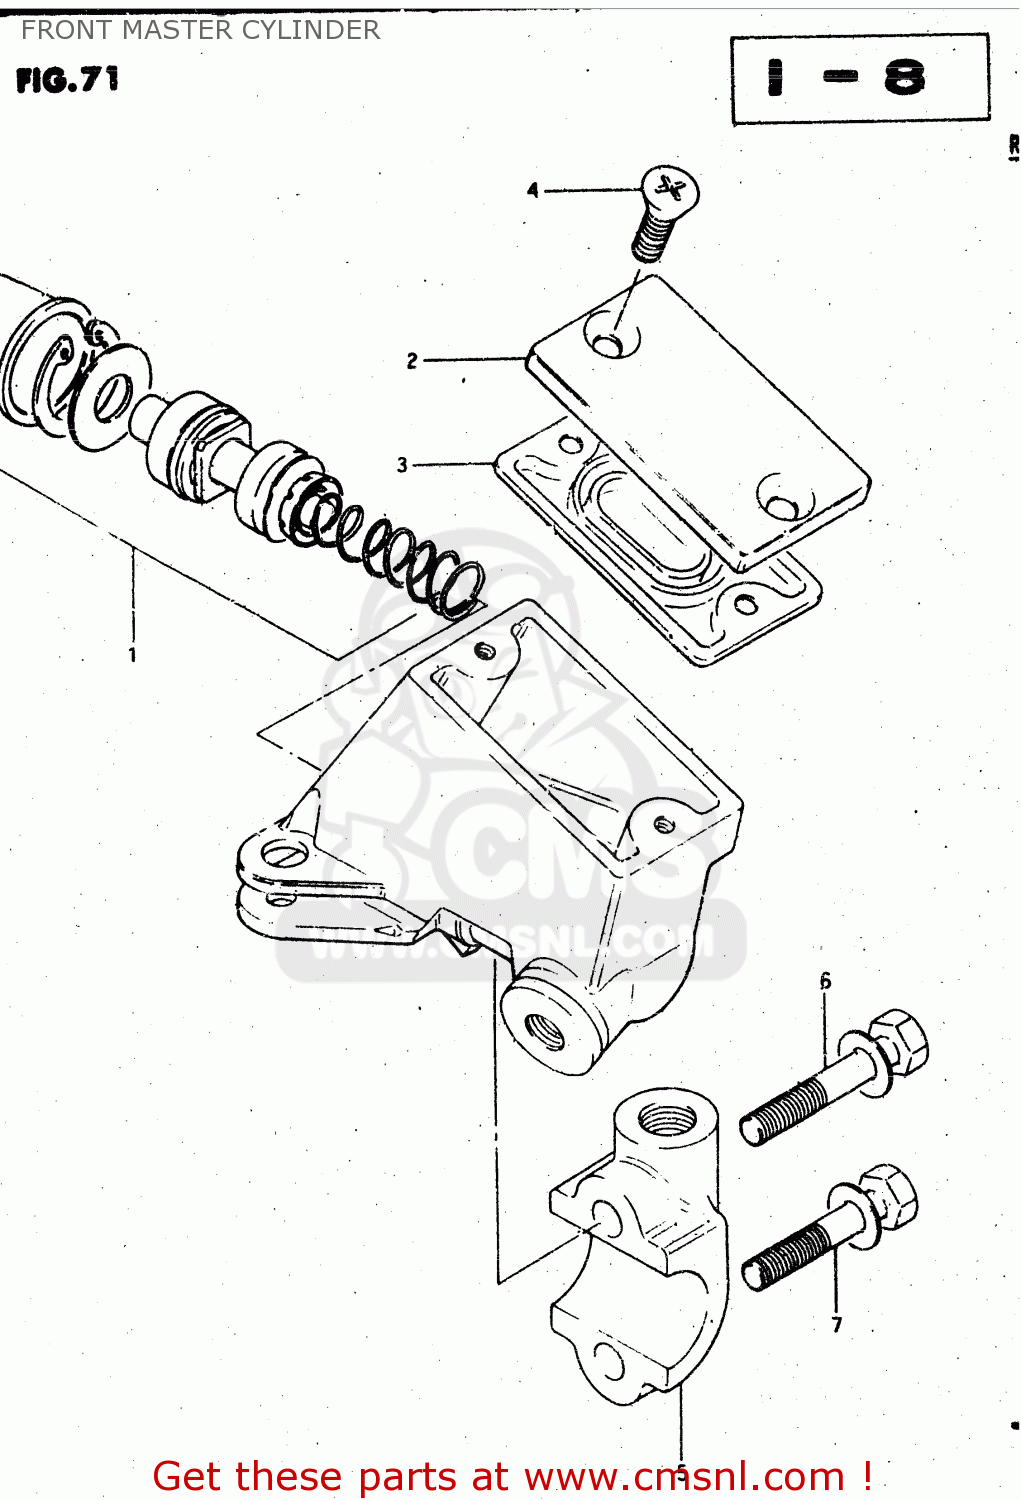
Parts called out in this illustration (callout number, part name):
1	PISTON & CUP SET
2	CAP
3	DIAPHRAGM,MASTER CYLINDER
4	SCREW
5	HOLDER
6	BOLT,MASTER CYLINDER H
7	BOLT
